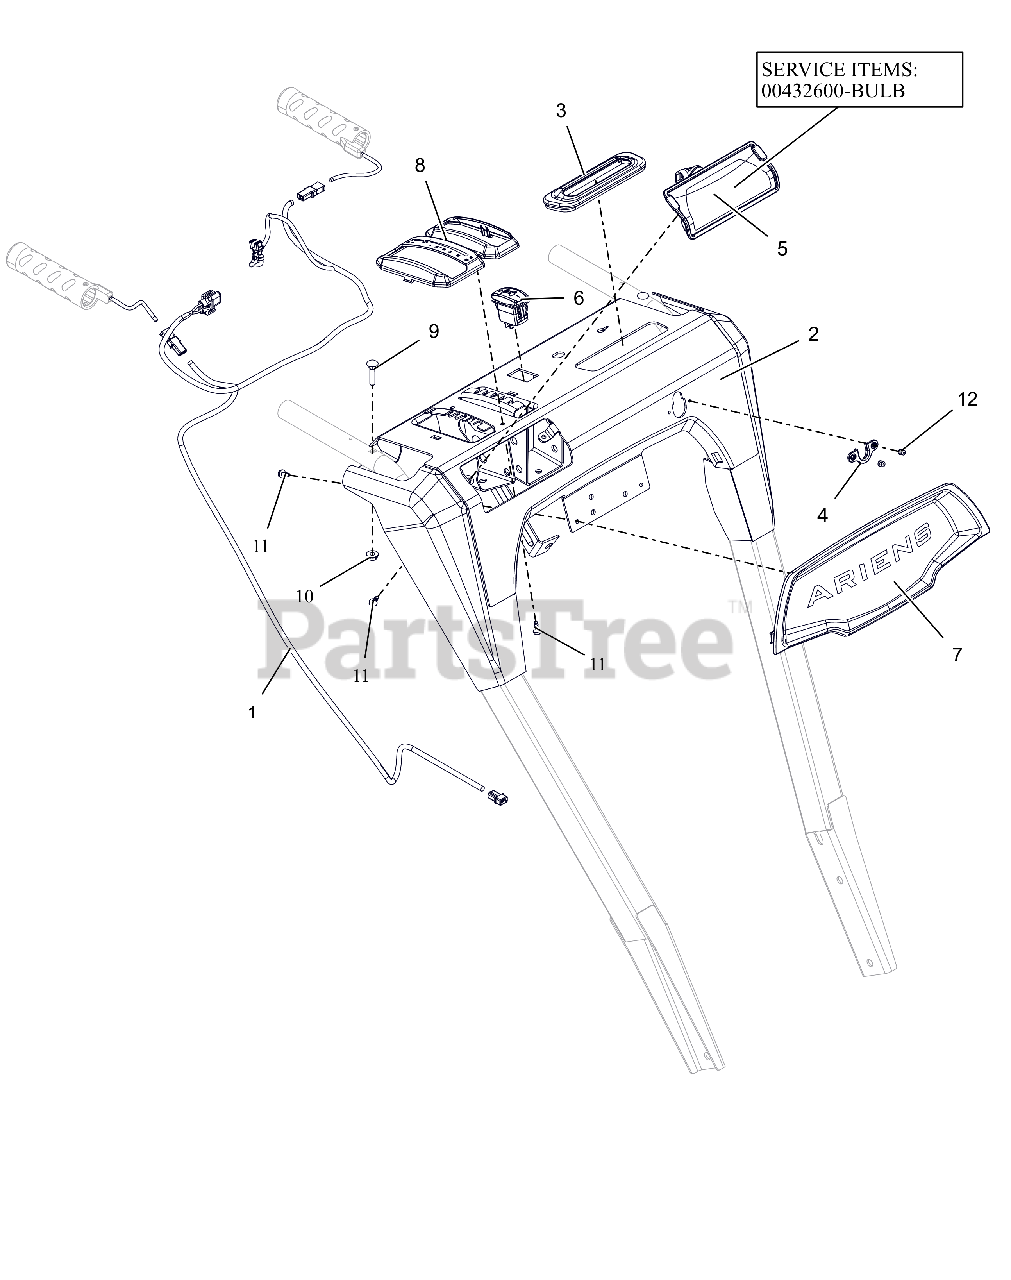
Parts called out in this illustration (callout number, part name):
1	HARNESS, LIGHT & WARMER
2	PANEL, DASH-FRICTION W/DECAL
3	GROMMET, BOOT, QUICK TURN
4	GROMMET, CABLE, QUICK TURN 2
5	HEADLIGHT ASY, HALO 20W 2SHOT
5	BULB, LIGHT-HALOGEN 20W
6	SWITCH,ROCKER SPST-ON/OFF
7	BEZEL, DASH - ARIENS LG DASH
8	BEZEL, SHIFT - FRICTION SNOW
9	BLT-RDHDXLSQNK.25-20X1.25 G5ZC
10	NUT-LK-CTR-FLG .25-20 ZC120
11	SCR, PLASTIC #10X.50
12	RVT-POP #43 .125X.313 STL ZINC
